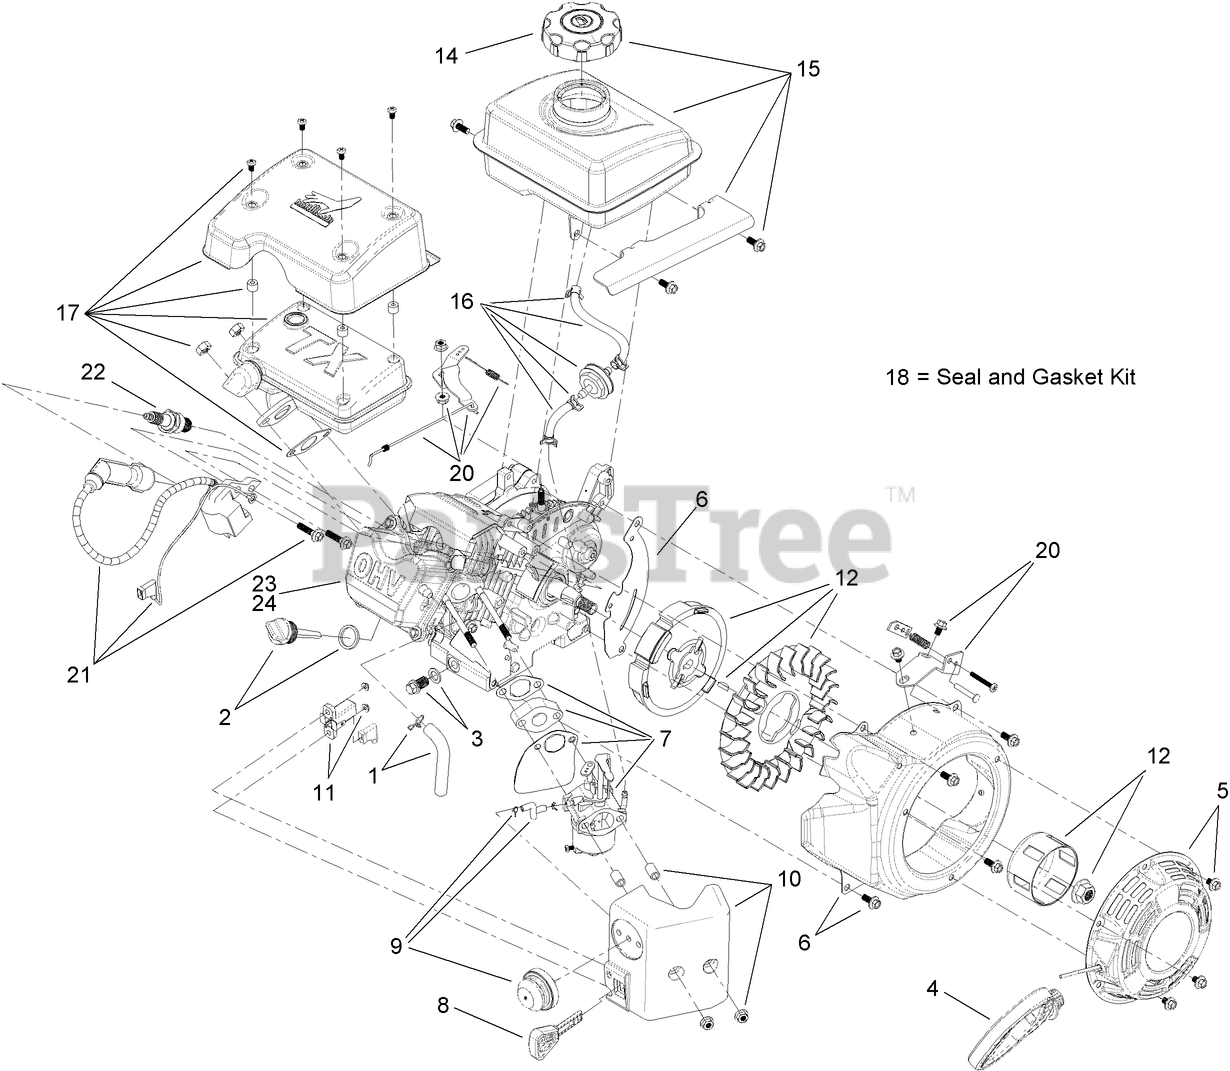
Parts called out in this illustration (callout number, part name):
1	BREATHER TUBE KIT
2	DIPSTICK AND O-RING KIT
3	DRAIN PLUG KIT
4	MITTEN GRIP KIT
5	RECOIL ASM KIT
6	BLOWER SHROUD KIT
7	COMPLETE CARB SERVICE KIT
7	NEEDLE REWORK KIT
7	CARB FLOAT AND NEEDLE KIT
8	KEY AND LANYARD KIT
9	PRIMER BULB KIT
10	HEATER BOX KIT
11	SWITCH KIT
12	FLYWHEEL AND FAN KIT
20	GOVERNOR KIT
22	SPARK PLUG
23	VALVE COVER ASM
24	GASKET-COVER, VALVE
